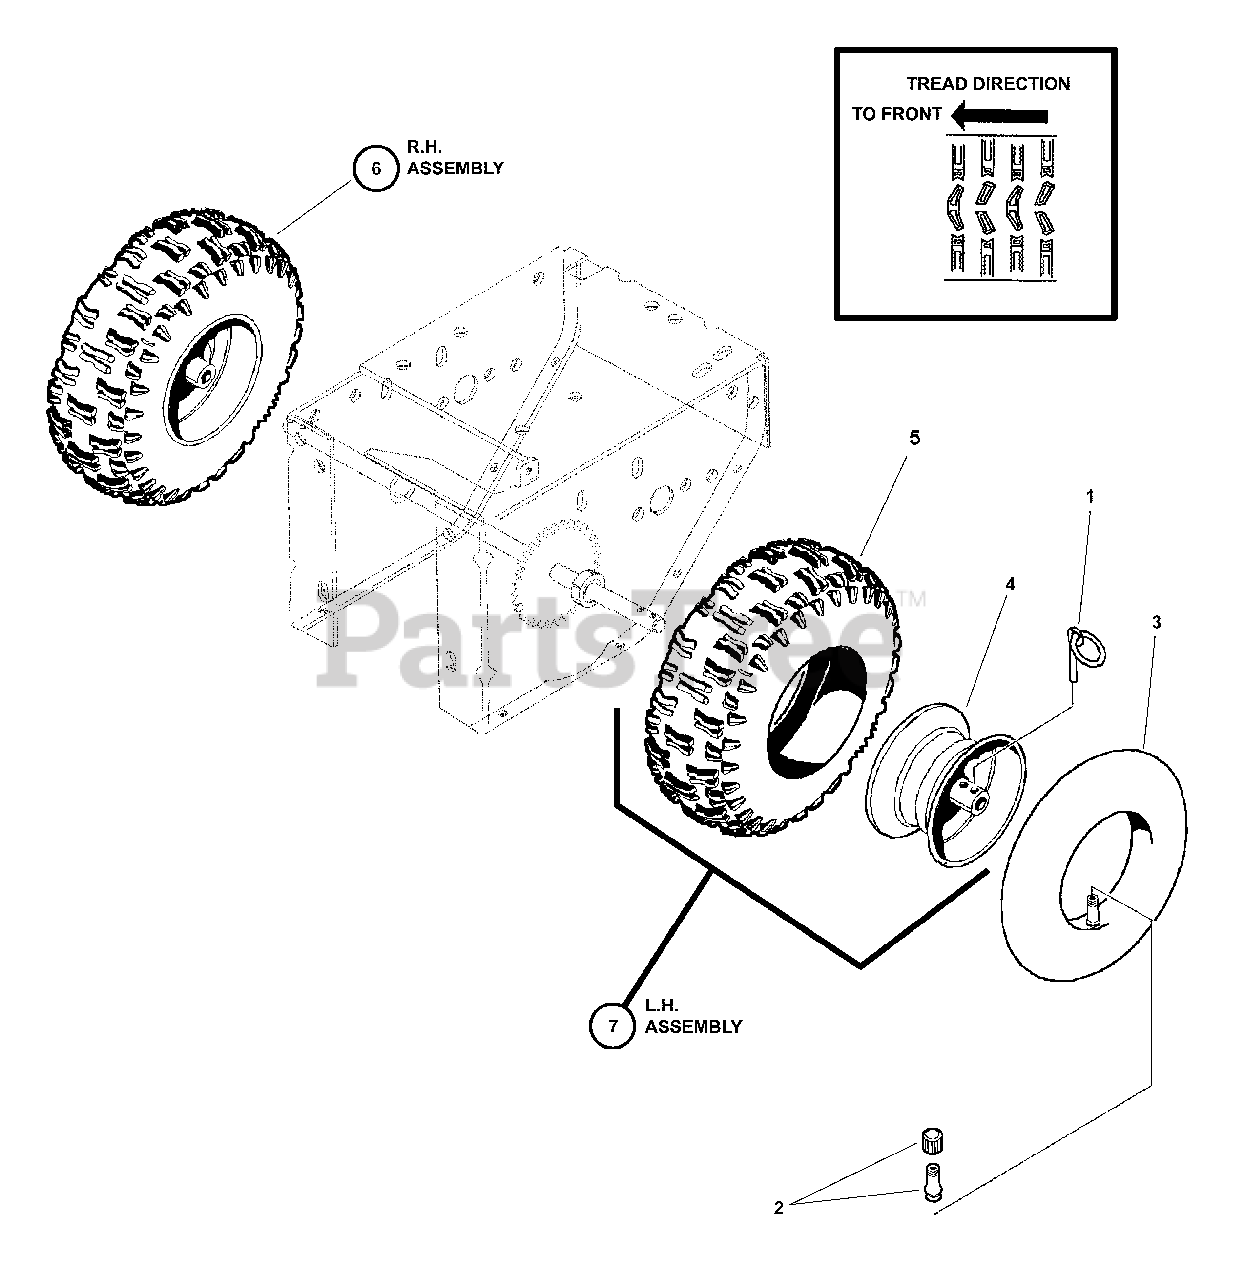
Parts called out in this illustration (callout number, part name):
1	KLIK- PIN, .310 ID x 1-3/4" Long
2	VALVE STEM AND CAP
3	TUBE, Tire
4	RIM, 6 x 3.25 (Weldment)
5	TIRE, 15 x 5.00-6, 2 Ply, Carlisle X-Trac
6	ASSY, Tire and Wheel, 15 x 5.00-6 Carlisle X-Trac, RH
7	ASSY, Tire and Wheel, 15 x 5.00-6 Carlisle X-Trac, LH
